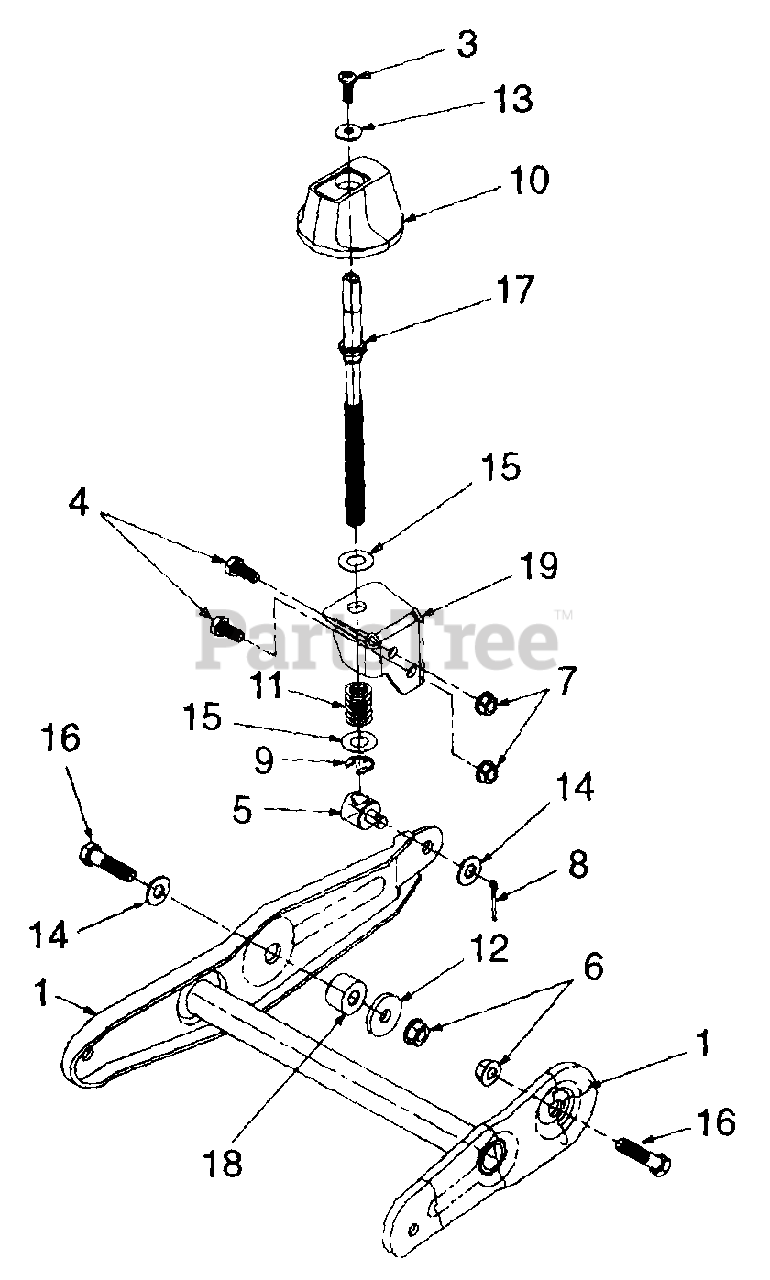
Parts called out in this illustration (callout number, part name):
1	Bracket Ass'y, Wheel Pivot
3	Screw, Pan Hd Mach, 1/4-20 x .75
4	Screw, Hex Cap, 5/16-18 x .75 GR5
5	Ferrule, Adjustment
6	Nut, Hex Flange Lock, 3/8-16
7	Nut, Hex Flange Lock, 5/16-18
8	Pin, Cotter, 1/8 x 1.0
9	E-Ring, .50 Dia
10	Knob
11	Spring, Compression
12	Washer, Flat, .406 x 1-1/4
13	Washer, Bell, .265 x .75 x .062
14	Washer, Flat, .406 x .875 x .059
15	Washer, Flat, .508 x 1.0 x .020
16	Shoulder Bolt, .75 x .43: 3/8-16
17	Rod, Height Adjustment
18	Spacer, .380 ID x 1.0 OD x .32 Lg
19	Bracket, Height Adj
